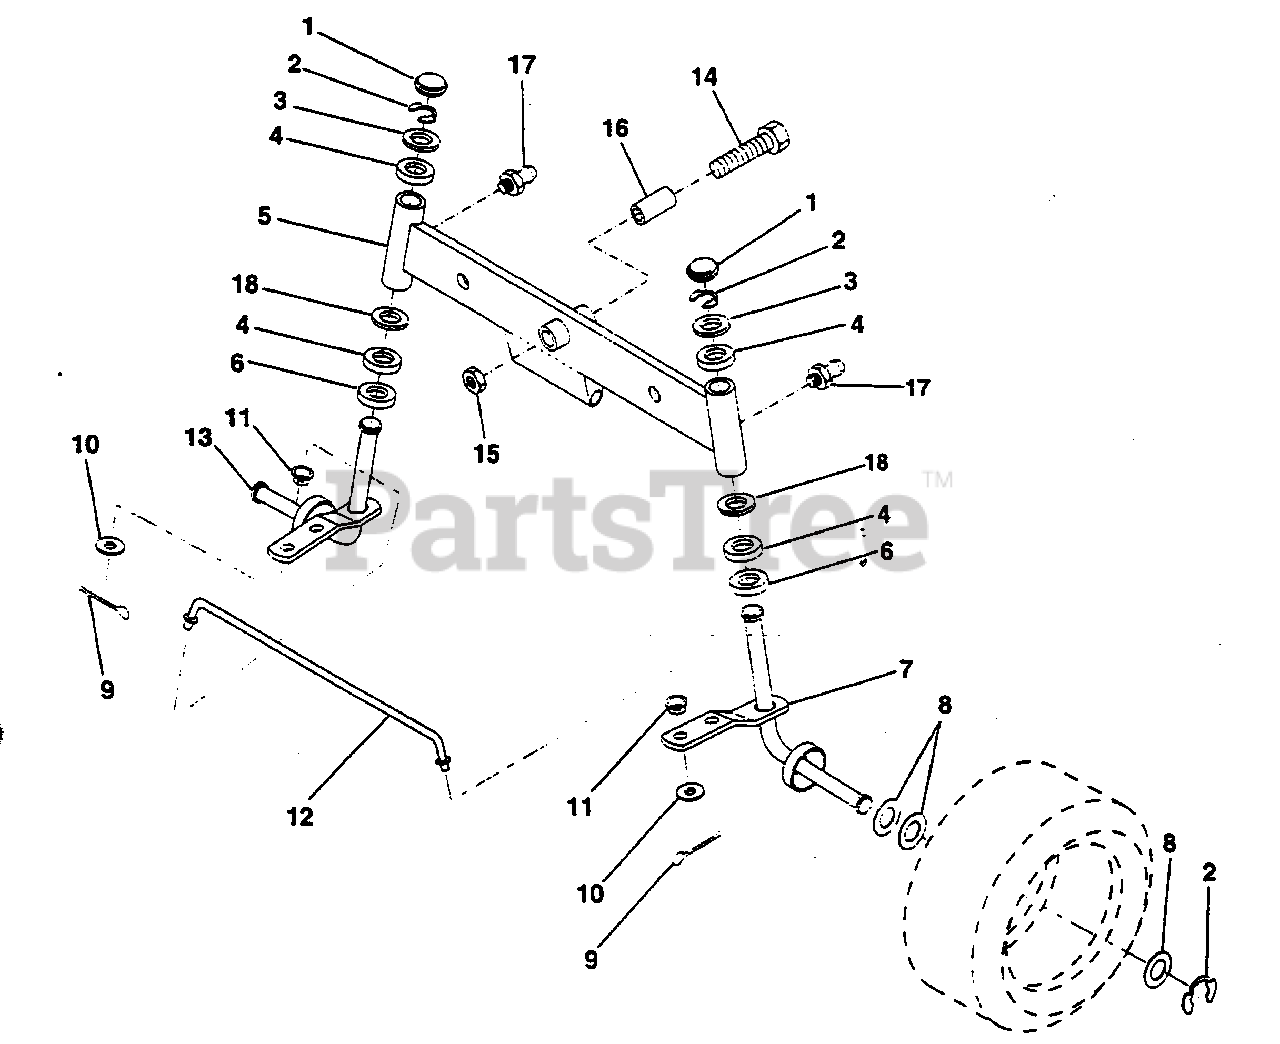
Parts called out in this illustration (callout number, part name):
1	Cap, Spindle (AYP part number)
2	Ring, Clip (AYP part number)
3	Washer 25/32 x 1-5/8 x 16 Gauge (AYP part number)
4	Bearing (AYP part number)
5	Axle, Front (AYP part number)
6	Bearing, Thrust (AYP part number)
7	Spindle Assembly, R.H. (AYP part number)
8	Washer 25/32 x 1-1/4 x 16 Gauge (AYP part number)
9	Pin, Cotter 1/8 x 3/4 (AYP part number)
10	Washer 13/32 x 13/16 x 16 Gauge (AYP part number)
11	Bushing (AYP part number)
12	Rod, Tie (AYP part number)
13	Spindle Assembly, L.H. (AYP part number)
14	Bolt, Hex Head 5/8-11 x 3-1/2 (AYP part number)
15	Locknut, Flange 5/8-11 (AYP part number)
16	Spacer, Bearing, Front Axle (AYP part number)
18	Washer 27/32 x 1-1/4 x 16 Gauge (AYP part number)
